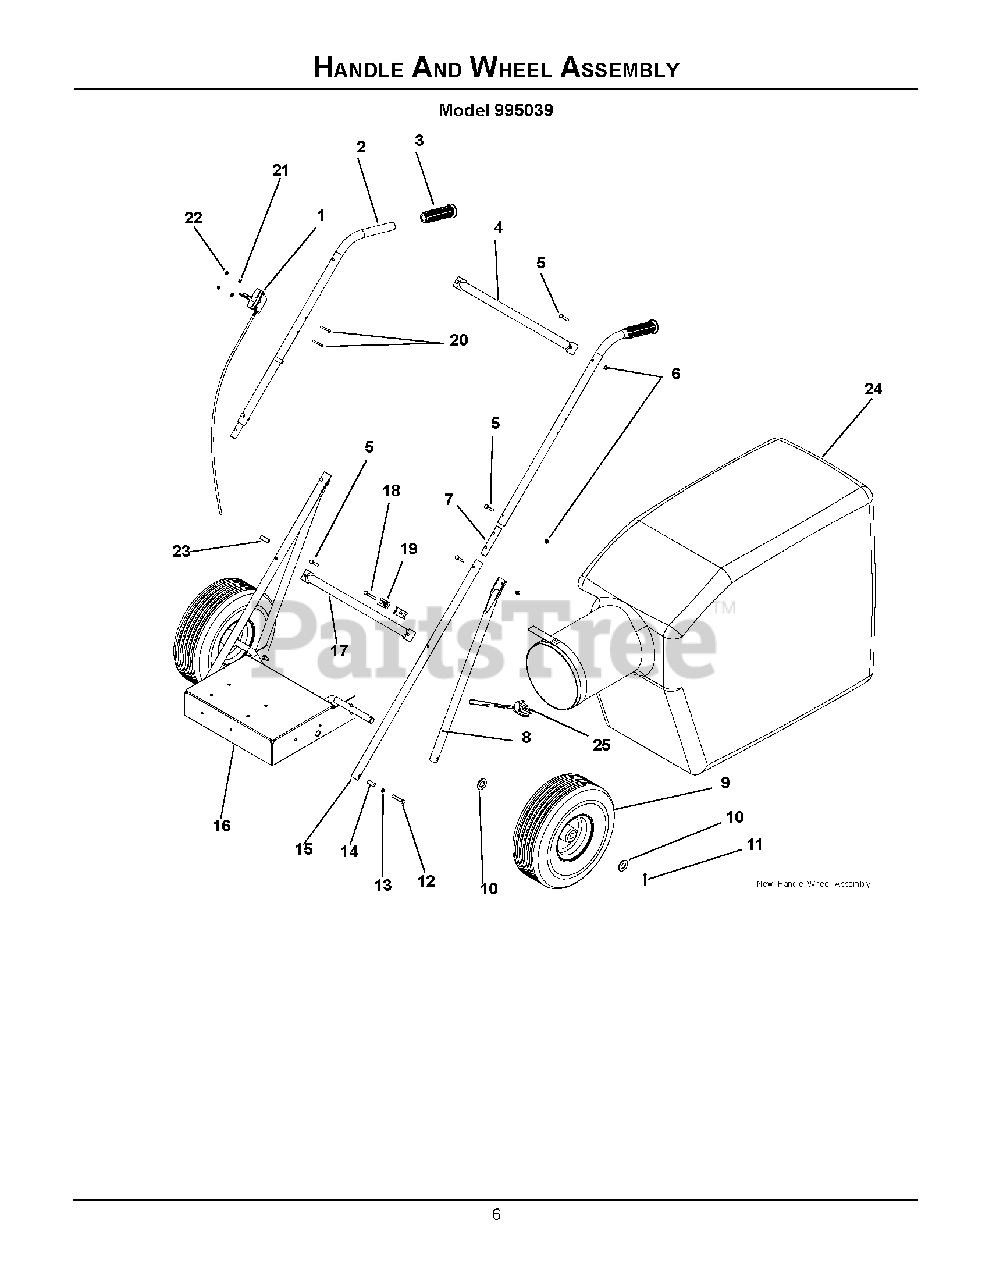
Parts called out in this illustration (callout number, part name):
5	9
6	12
10	4
12	2
13	8
18	1
21	2
22	2
